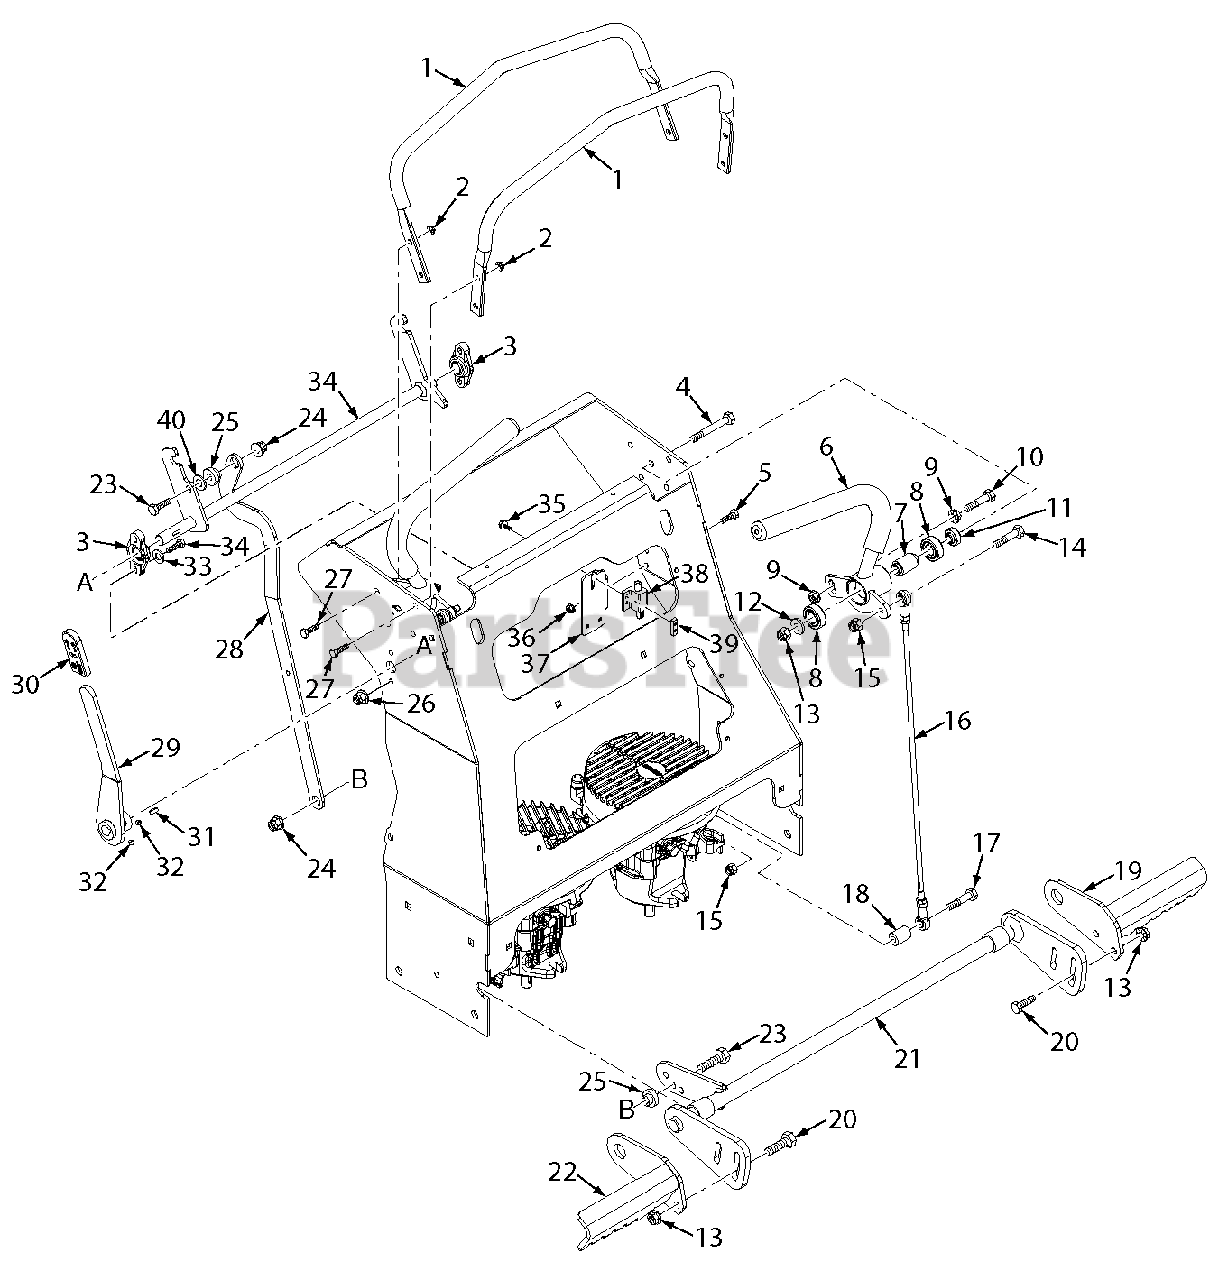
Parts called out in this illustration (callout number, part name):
1	Reference Bar
2	Nut, Serrated Flange 5/16-18
3	Bearing
4	Bolt, Hex Head 3/8-16 x 3-1/4"
5	Bolt, Hex Head 1/4-20 x 3/4"
6	Handlebar Assy., LH
6	Handllevar Assy., RH
7	Spacer, Bearing
8	Bearing
9	Nut, Serrated Flange 3/8-16
10	Bolt, Hex Head 3/8-16 x 2"
11	Spacer, Controls
12	Flatwasher, 3/8-.391 x .938 x .105 HD
13	Nut, Elastic Stop 3/8-16
14	Bolt, Hex Head 5/16-18 x 1-1/4"
15	Nut, Elastic Stop 5/16-18
16	Linkage Assy., Steering
17	Hex Head Socket, 5/16-18 x 1" (36)
17	Bolt, Hex Head 5/16-18 x 2"
18	Spacer (excludes SVRII-36A)
19	Brake Paddle Weldment, RH (36)
19	Brake Paddle Weldment, RH
20	Bolt, Carriage 3/8-16 x 1"
21	Bellcrank Weldment, Brake (36)
21	Bellcrank Weldment, Brake
22	Brake Paddle Weldment, LH
23	Bolt Hex Head 3/8-16 x 1-1/4"
24	Nut, Flange Elastic Stop 3/8-16
25	Bushing, Oilite
26	Nut, Flange Elastic Stop 1/4-20
27	Bolt, Hex Head 5/16-18 x 3/4"
28	Link, Brank Engage (36)
28	Link, Brake Engage
29	Brake Lever Assy. - SVRII
30	Grip, Brake Lever
31	Key, Woodruf #604 3/16 x 5/8
32	Set Screw 1/4-20 x 1/4"
33	Flatwasher, 1/4-.281 x .625 x .065
34	Lock Weldment, Neutral
35	Screw, #10-32 x 3/4" Taptite
36	Nut, Serrated Flange 1/4-20
37	Bracket, Neutral Switch
38	Switch, Interlock (36)
38	Switch, Interlock
39	Plate, Threaded
40	Flatwasher, 3/8-.391 x .938 x .105
